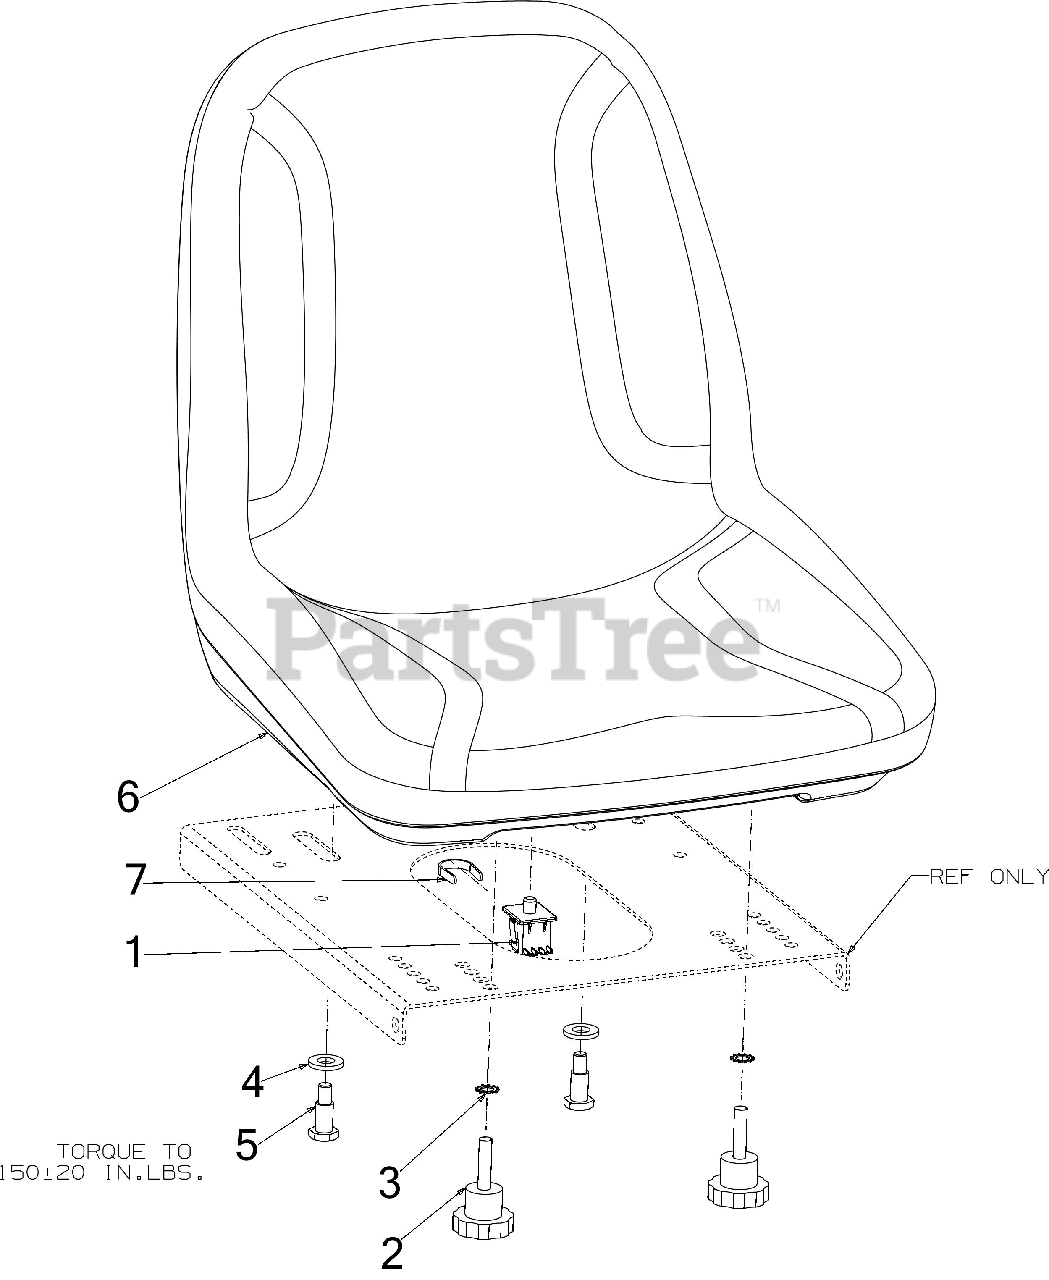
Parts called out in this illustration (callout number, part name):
1	SEAT SWITCH
2	SEAT ADJUST KNOB
3	LOCK WASHER 3/8
4	FLAT WASHER .510 x 1.000 x .125
5	SHOULDER SCREW .500
6	SEAT-18" 4 PT MTG
7	RETAINING CLIP
